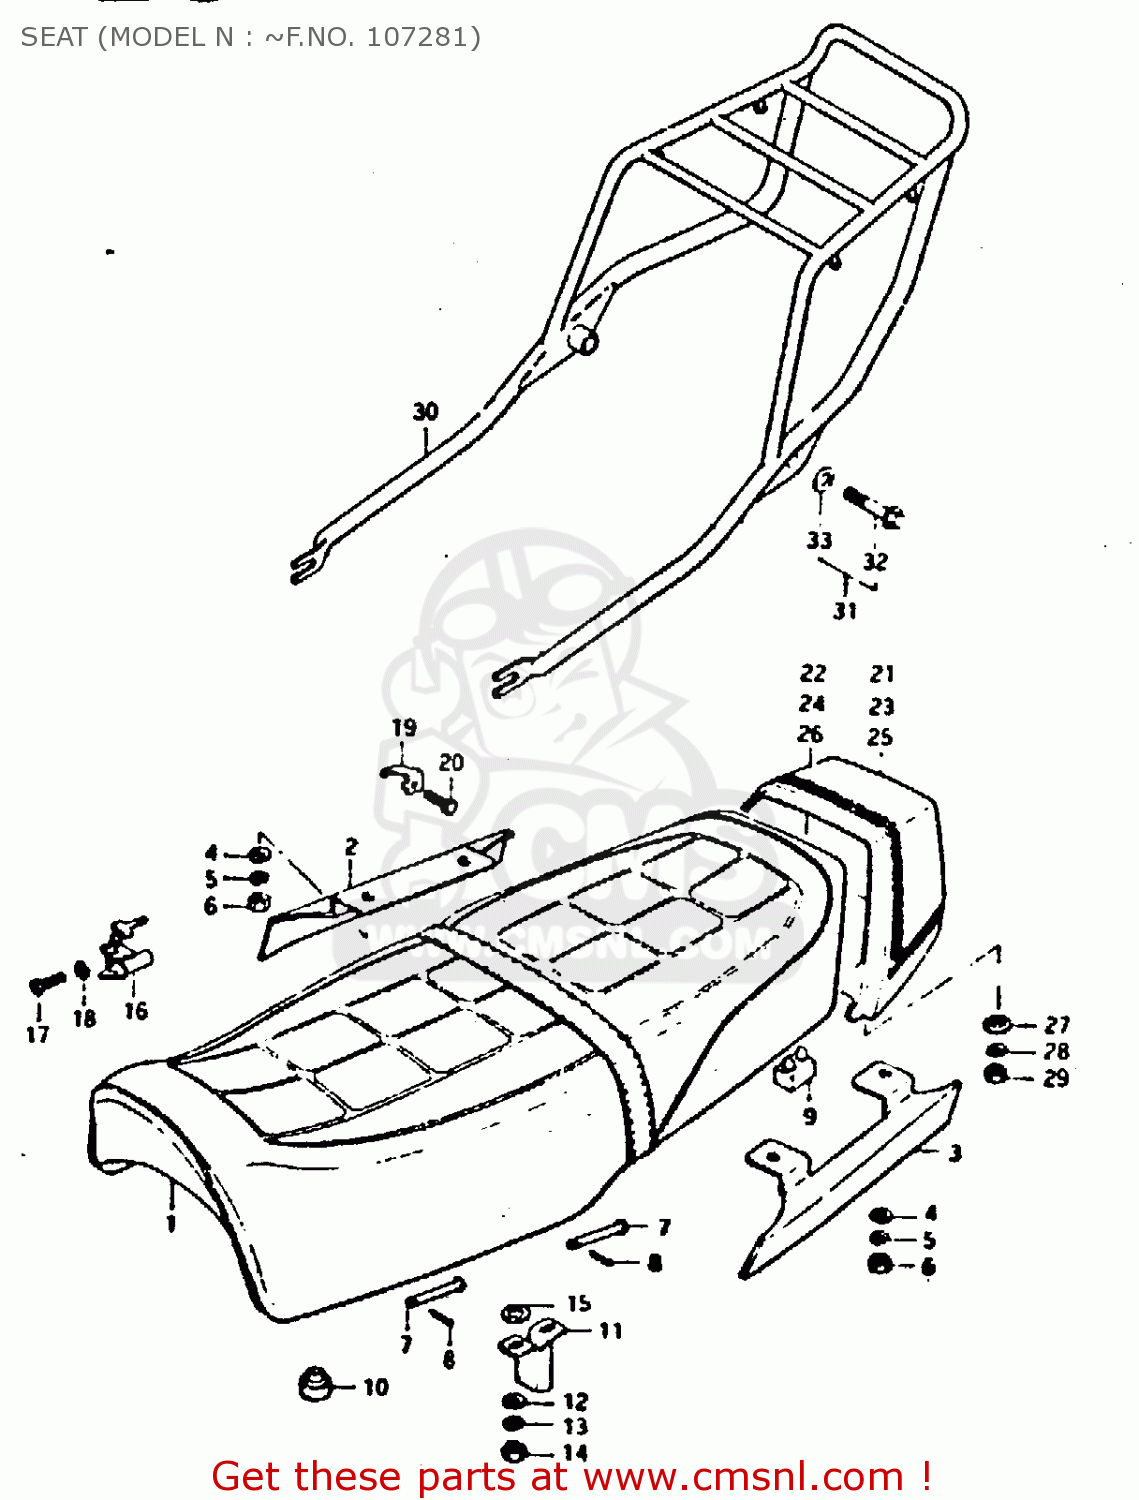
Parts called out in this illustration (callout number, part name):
1	SEAT (BLACK)
2	MOULDING, RH (RED)
3	MOULDING, LH (RED)
4	WASHER
5	LOCK WASHER
6	NUT
7	PIN
8	PIN
9	CUSHION
10	CUSHION
11	STRIKER,SEAT LOCK
12	WASHER
13	LOCK WASHER
14	NUT 6MM
15	WASHER(6.5X18X1)
16	LOCK ASSY,SEAT
17	SCREW
18	LOCK WASHER
19	SPRING,HELMET HOLDER
20	BOLT 5X16
21	COVER, SEAT TAIL (RED)
22	TAPE (BLACK)
23	COVER, SEAT TAIL (BLUE)
24	TAPE (WHITE)
27	WASHER
28	LOCK WASHER
29	NUT 6MM
30	CARRIER, SPORTS
31	BOLT SET, CARRIER
32	BOLT
33	WASHER(10.3X25X1.5
